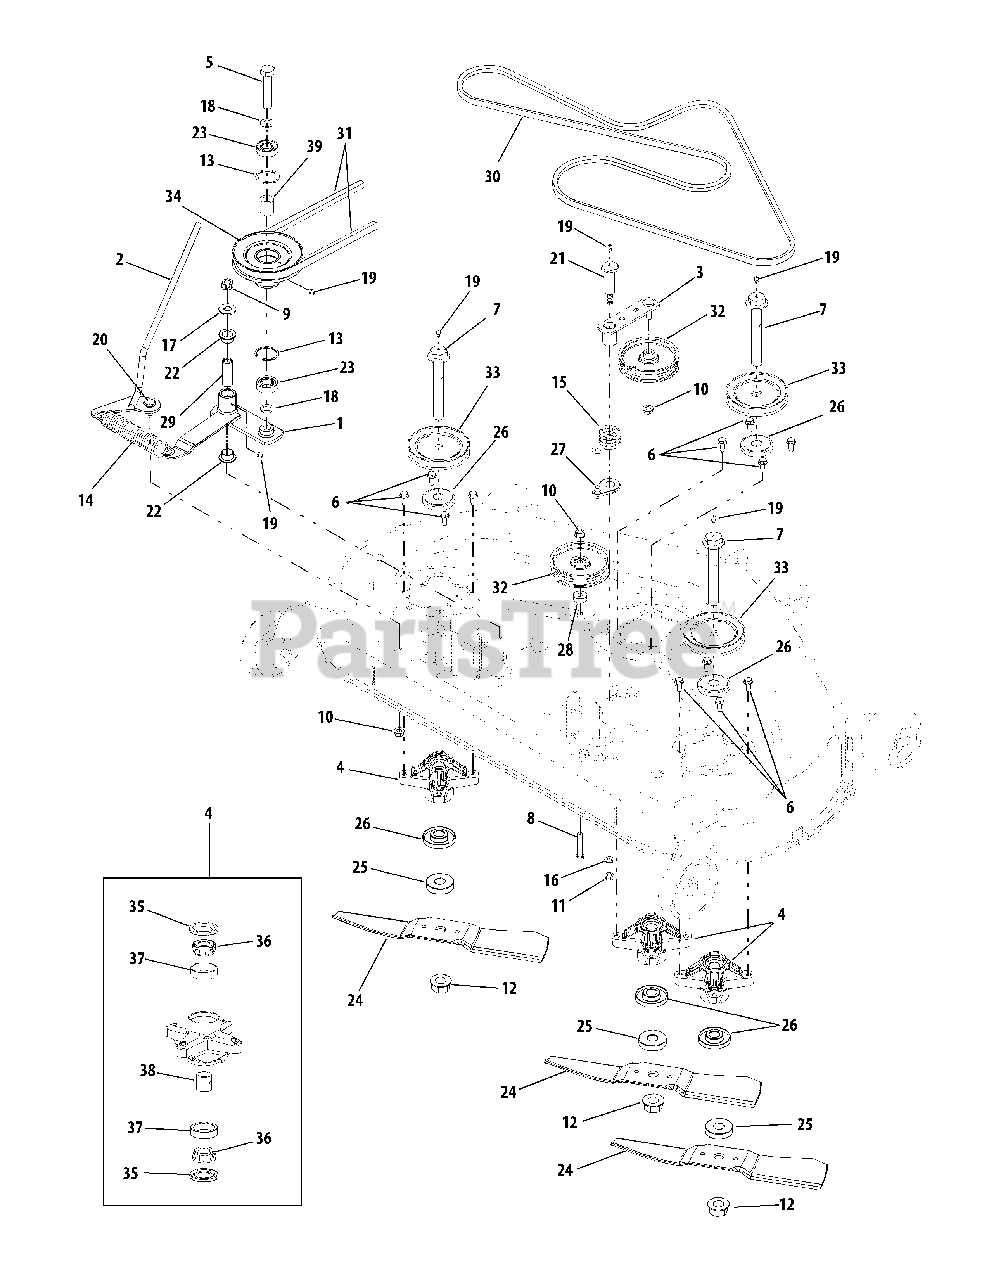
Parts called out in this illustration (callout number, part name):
1	Idler Assembly
2	Handle, Tension
3	Idler Arm Assembly
4	Spindle Ass’y, Incl. Ref. Nos. 35 thru 38
5	Screw, Hex Cap, 5/8-18 x 3.0
6	Screw, Hex Wash Ld, 5/16-18 x .75
7	Bolt, Spindle, 3/4-16 x 5.37
8	Screw, Hex Cap, 3/8-16 x 2.0 GR5
9	Nut, Hex Lock, 1/2-20
10	Nut, Flange Lock, 3/8-16
11	Nut, Hex, 7/16-14, GR2
12	Nut, Hex Flange, 3/4-16
13	Snap Ring, Internal
14	Spring, Ext, .162 Dia x 1.25 OD
15	Torsion Spring, Idler, 1.10 ID x 1.3
16	Washer, Lock, 7/16
17	Washer, Flat, 1/2 x 1.25 x .10
18	Washer, Flat, .65 x 1.25 x .075
19	Fitting, Lube, 3/16 Drive
20	Bolt, Shoulder, .498 Dia x .340
21	Screw, Shldr, .68 x 2.11, 7/16-14
22	Bearing, Flange, 3/4 ID x .52 LG
23	Bearing, Ball
24	Blade, Mower, 15.94
25	Spacer, Blade
26	Spacer, Deck Spindle
27	Retainer, Spring
28	Spacer, .406 ID x 1.00 OD x .38
29	Spacer, .5 OD x .75 x 2.07 Lg
30	V-Belt, 1/2 x 103.0 Lg
31	V-Belt, B sect x 111.2 Lg
32	Pulley, Idler, 4.25 Dia
33	Pulley, V-Type, 4.0 Dia
34	Pulley, Double
35	Seal, Oil, 1.25 x 1.874 x .25
36	Bearing, Cone
37	Cup, Bearing
38	Spacer, Bearing
39	Spacer, .88 x .635 x 1.25
